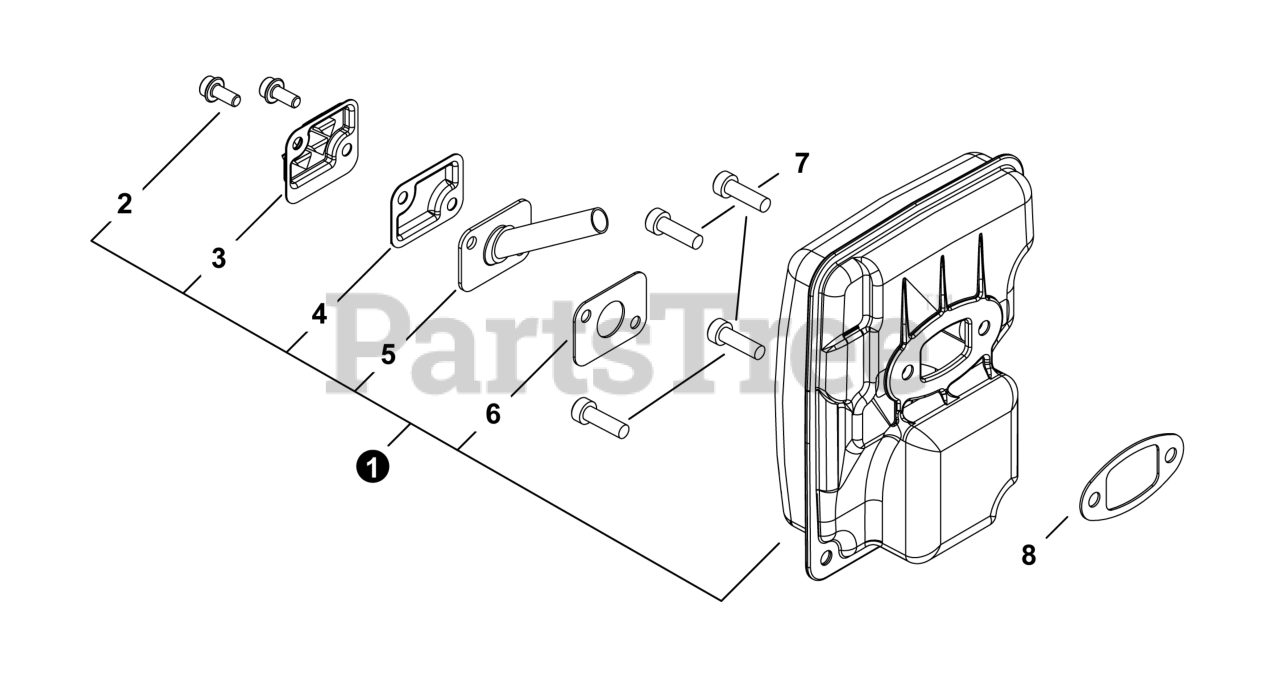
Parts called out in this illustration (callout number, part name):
1	MUFFLER ASSY
2	BOLT, FLANGE
3	GUIDE, EXHAUST
4	SCREEN, SPARK ARRESTER
5	PLATE, MUFFLER
6	GASKET, MUFFLER
7	BOLT 6×18
8	GASKET, EXHAUST
